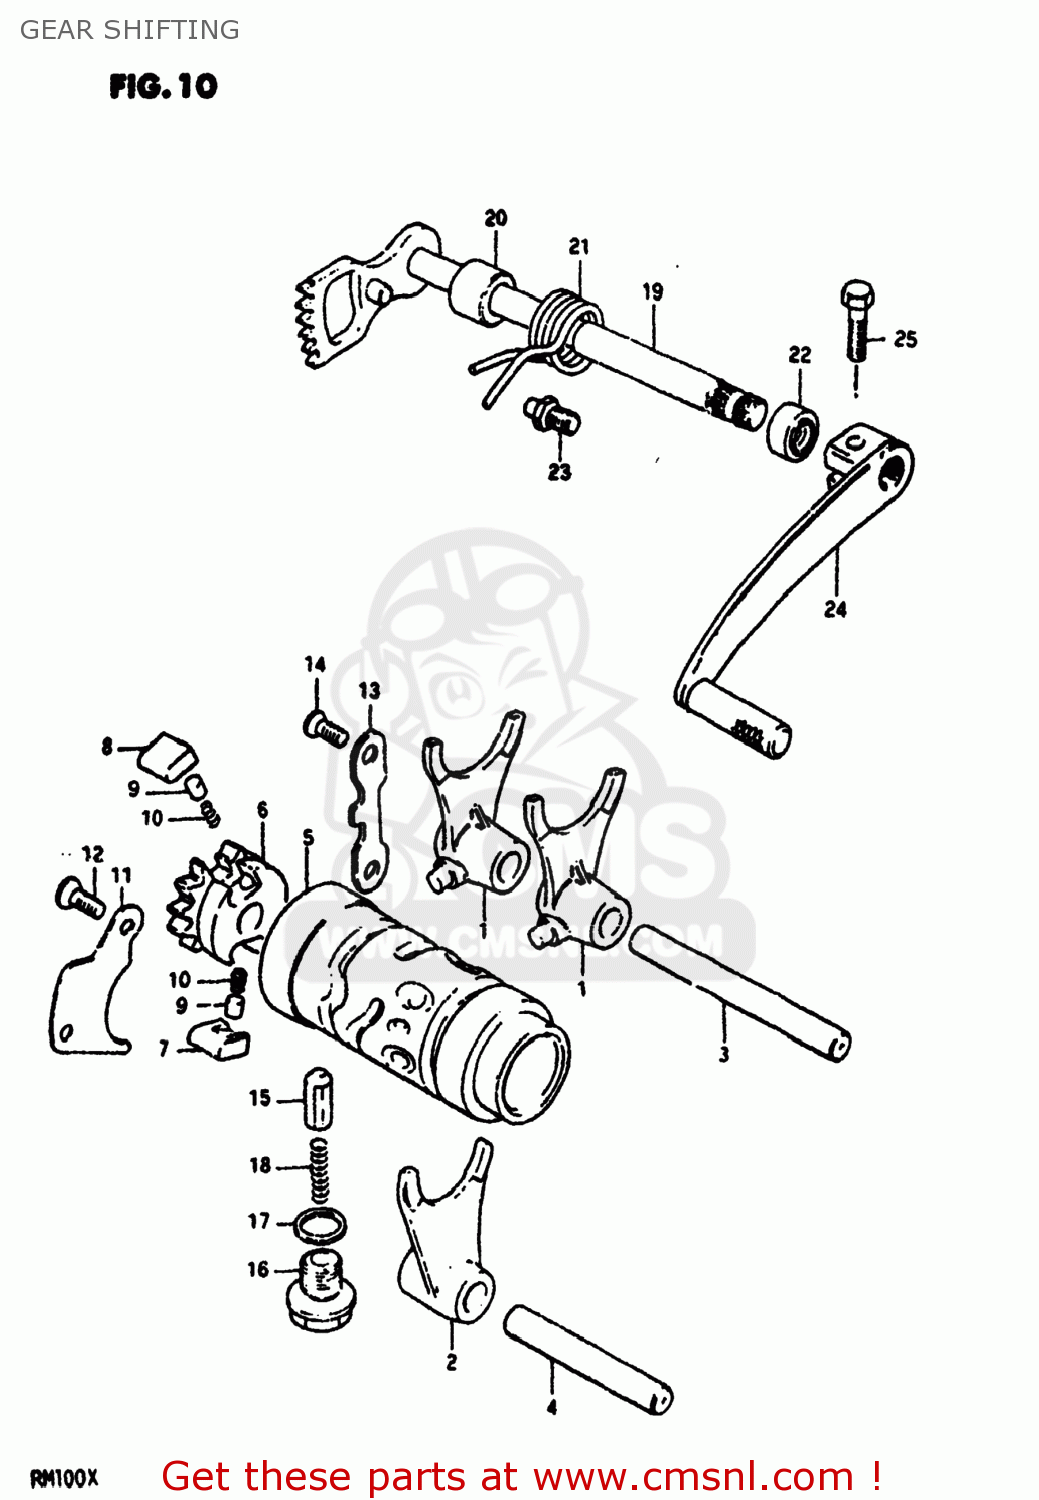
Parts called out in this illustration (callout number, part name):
1	FORK,GEAR SHIFT NO.1
2	FORK,GEAR SHIFT NO.2
3	SHAFT,GEAR SHIFT FORK
4	SHAFT,GEAR SHIFT FORK
5	CAM,GEAR SHIFT
6	RETAINER,GEAR SHIFT CAM
7	PAWL,GEAR SHIFT NO.1
8	PAWL,GEAR SHIFT NO.2
9	PIN(5X8)
10	SPRING
11	LIFTER,GEAR SHIFT PAWL
12	SCREW
13	GUIDE,GEAR SHIFT CAM
14	SCREW
15	STOPPER,GEAR SHIFTING
16	BOLT,GEAR SHAFT CAM STOPPER
17	GASKET(14X19.2X2) (NAS)
18	SPRING
19	SHAFT,GEAR SHIFT
20	SPACER(12X20X15.3)
21	SPRING
22	OIL SEAL
23	STOPPER,GEAR SHIFT CAM
24	LEVER ASSEMBLY,GEAR SHIFTING
25	BOLT
